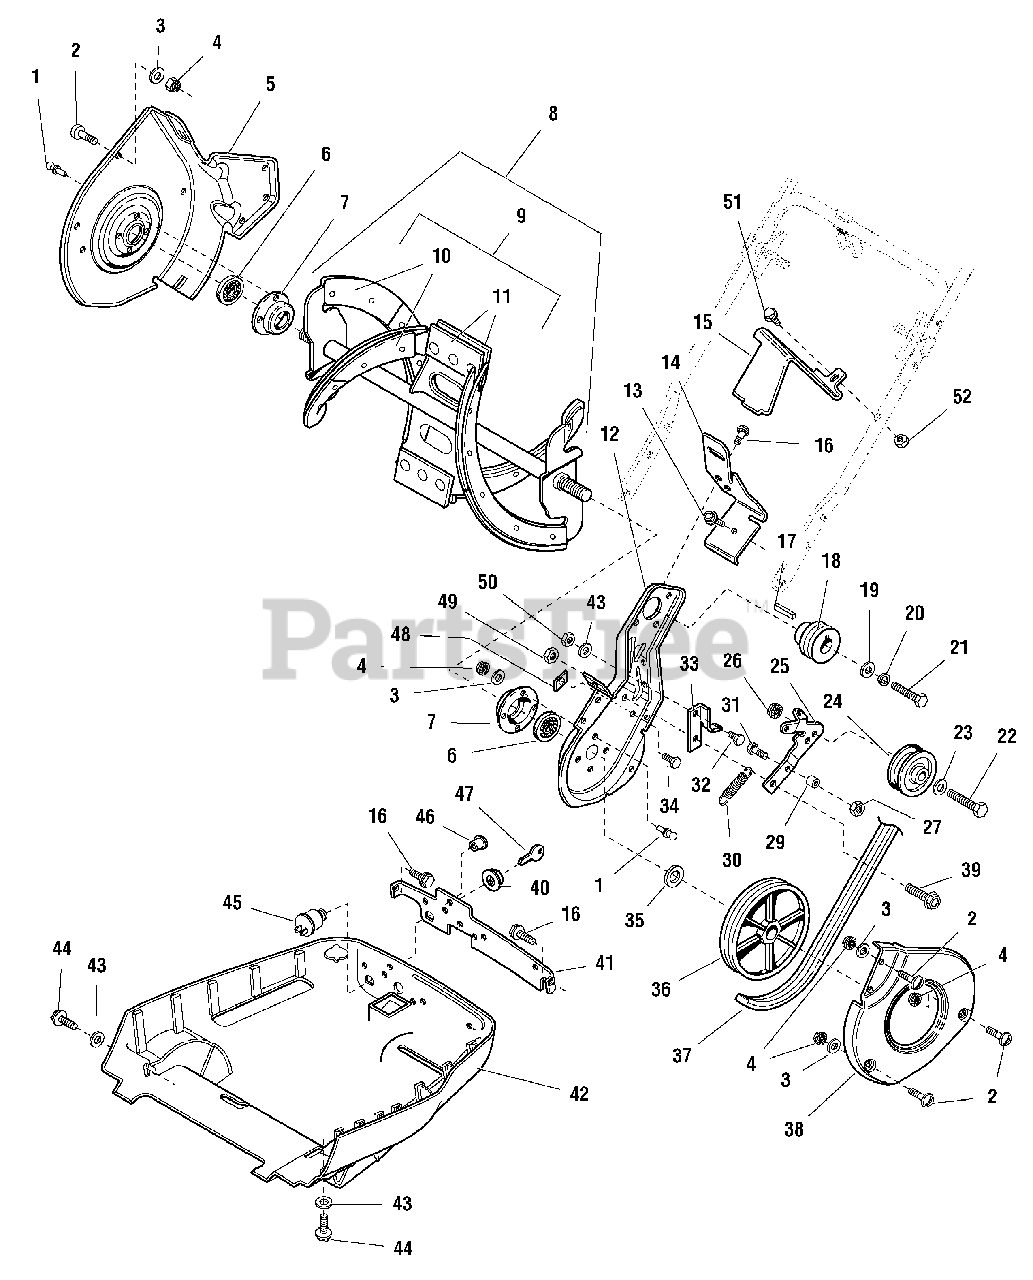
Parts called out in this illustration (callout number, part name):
1	RIVET, Pop, 1/4 x 1/2
2	SCREW, Truss Head, Torx, #10-24
3	WASHER, Rivet
4	NUT, Hex Lock. ESNA, #10-24
5	FRAME, Right Side
6	BEARING, Auger
7	RETAINER, Bearing
8	AUGER ASSEMBLY, Complete (Includes Ref. Nos. 9-11)
9	KIT, Flighting Replacement (Includes Ref. Nos. 10 & 11, plus mounting hardware)
10	FLIGHT, Rubber
11	CENTER FLIGHT, Rubber
12	FRAME, Left Side
13	SCREW, Plastite, #10-14 x 5/8
14	SHIELD, Belt
15	AIR DEFLECTOR
16	SCREW, Hex Head, #10-24 x 1-1/4
17	KEY, Parallel
18	PULLEY, Drive
20	LOCKWASHER, 5/16
21	CAPSCREW, Hex Head, 5/16-24 x 1-1/4
22	CAPSCREW, Hex Head, 3/8-16 x 1-1/2
23	WASHER
24	PULLEY, Idler
26	NUT, Flange Whiz Lock, 3/8-16
27	NUT, Hex Centerlock, 1/4-20
29	ROLLER, Belt Stop
30	SPRING, Idler Return
31	CAPSCREW, Hex Head, 1/4-20 x 1
32	CAPSCREW, Hex Head, 1/4-20 x 7/8
33	BRACKET, Belt
34	CAPSCREW, Hex Washer Head Taptite, 1/4-20 x 5/8
35	SPACER, Pulley
36	PULLEY, Driven
37	BELT, Drive
38	GUARD, Belt
39	IDLER PIVOT BOLT
40	FLANGE NUT, Ignition Switch, 5/8-32
41	CONTROL PANEL
42	LOWER HOUSING
43	WASHER
44	SCREW, Hex Head, Taptite, 1/4-20 x 7/8
45	SWITCH, Ignition
46	SNAP BUSHING, 1/4
47	KEY, Ignition
48	SPEED NUT, 1/4-20
49	NUT, Hex Lock, ESNA, 5/16-18
50	NUT, Hex Lock, ESNA, 1/4-20
51	SCREW, Hex Head, Taptite, #10-24 x 1/2
52	NUT, Hex Lock, #10-24
